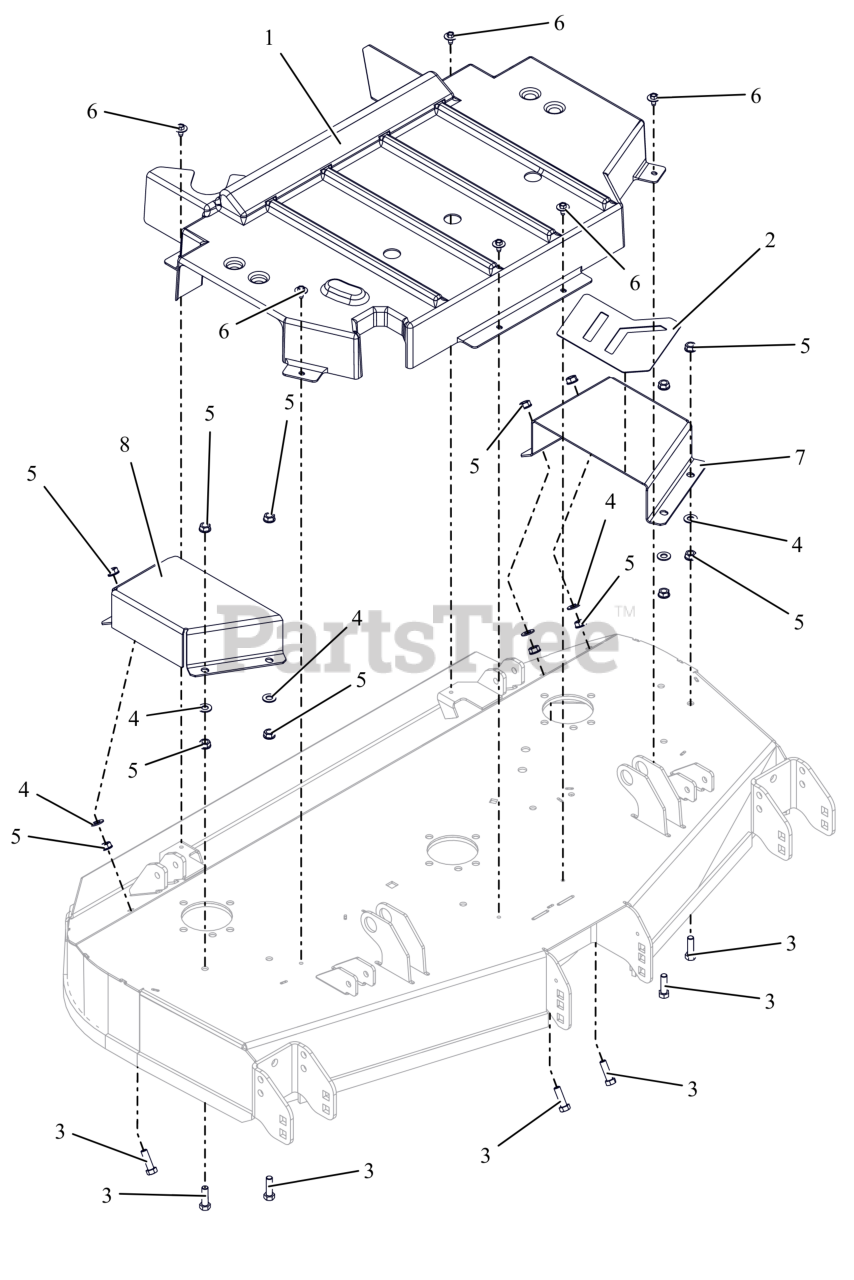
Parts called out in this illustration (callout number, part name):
1	GUARD, CENTER DECK SPINDLE CE
2	GRIP TAPE 48 BELT COVER
3	BLT, HEX .38-16X1.25 G5 ZCC
4	WSHR,FLT .406X.812X.065 ZCC
5	NUT, SPNLK-FLG .38-16 G5 ZCC
6	SCR, TAP .25-20X.50 LG HWH ZCC
7	GUARD, BELT 48 LH CE RD
8	GUARD, BELT 48 RH CE RD
